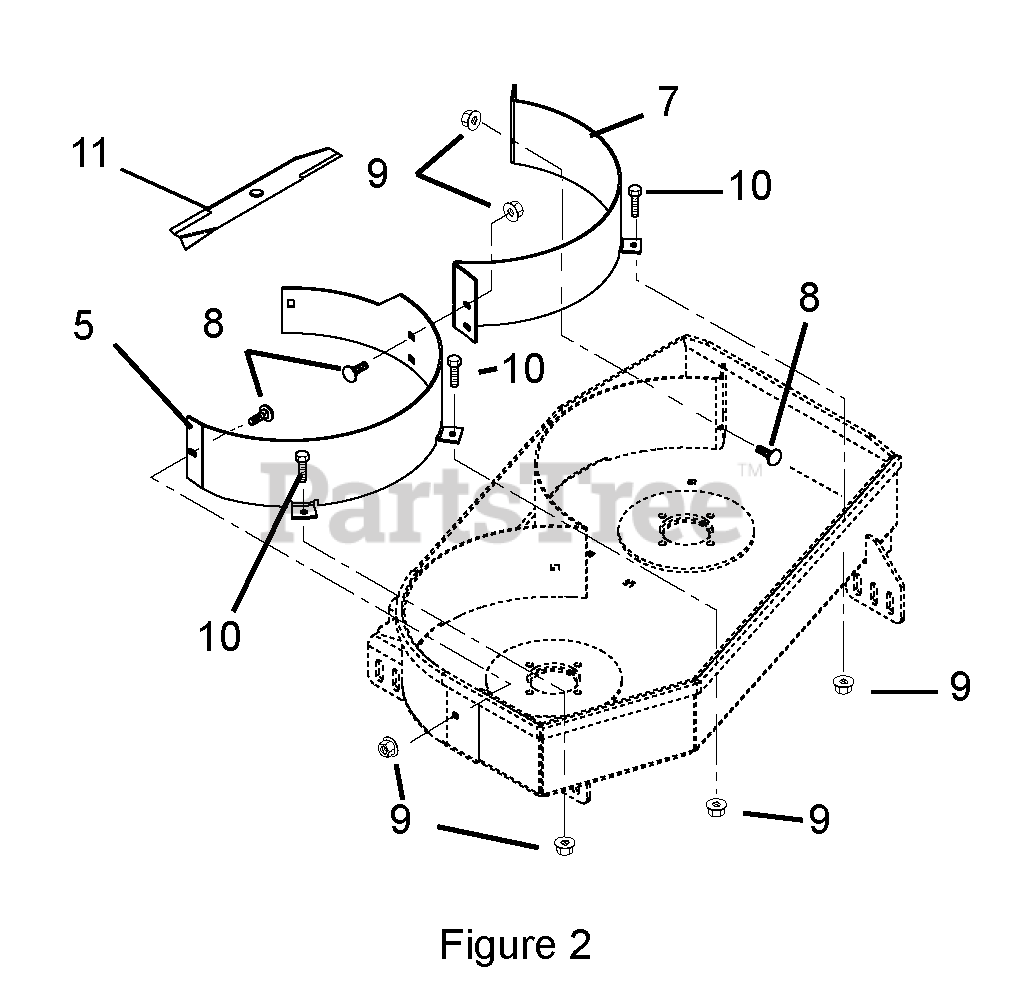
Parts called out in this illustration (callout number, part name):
5	32" Left Mulch Baffle
5	36" Left Mulch Baffle
5	44" Left Mulch Baffle
5	48" Left Mulch Baffle
5	52" Left Mulch Baffle
5	34" Left Mulch Baffle
7	32" Right Mulch Baffle
7	36" Right Mulch Baffle
7	44" Right Mulch Baffle
7	48" Right Mulch Baffle
7	52" Right Mulch Baffle
7	34" Right Mulch Baffle
8	Round Head Square Neck Bolt, 5/16-18 x 3/4
9	Top-Locking Flange Nut, 5/16-18
10	Hex Bolt, 5/16-18 x 3/4
11	Blade, Mulch
11	Mulch Blade
